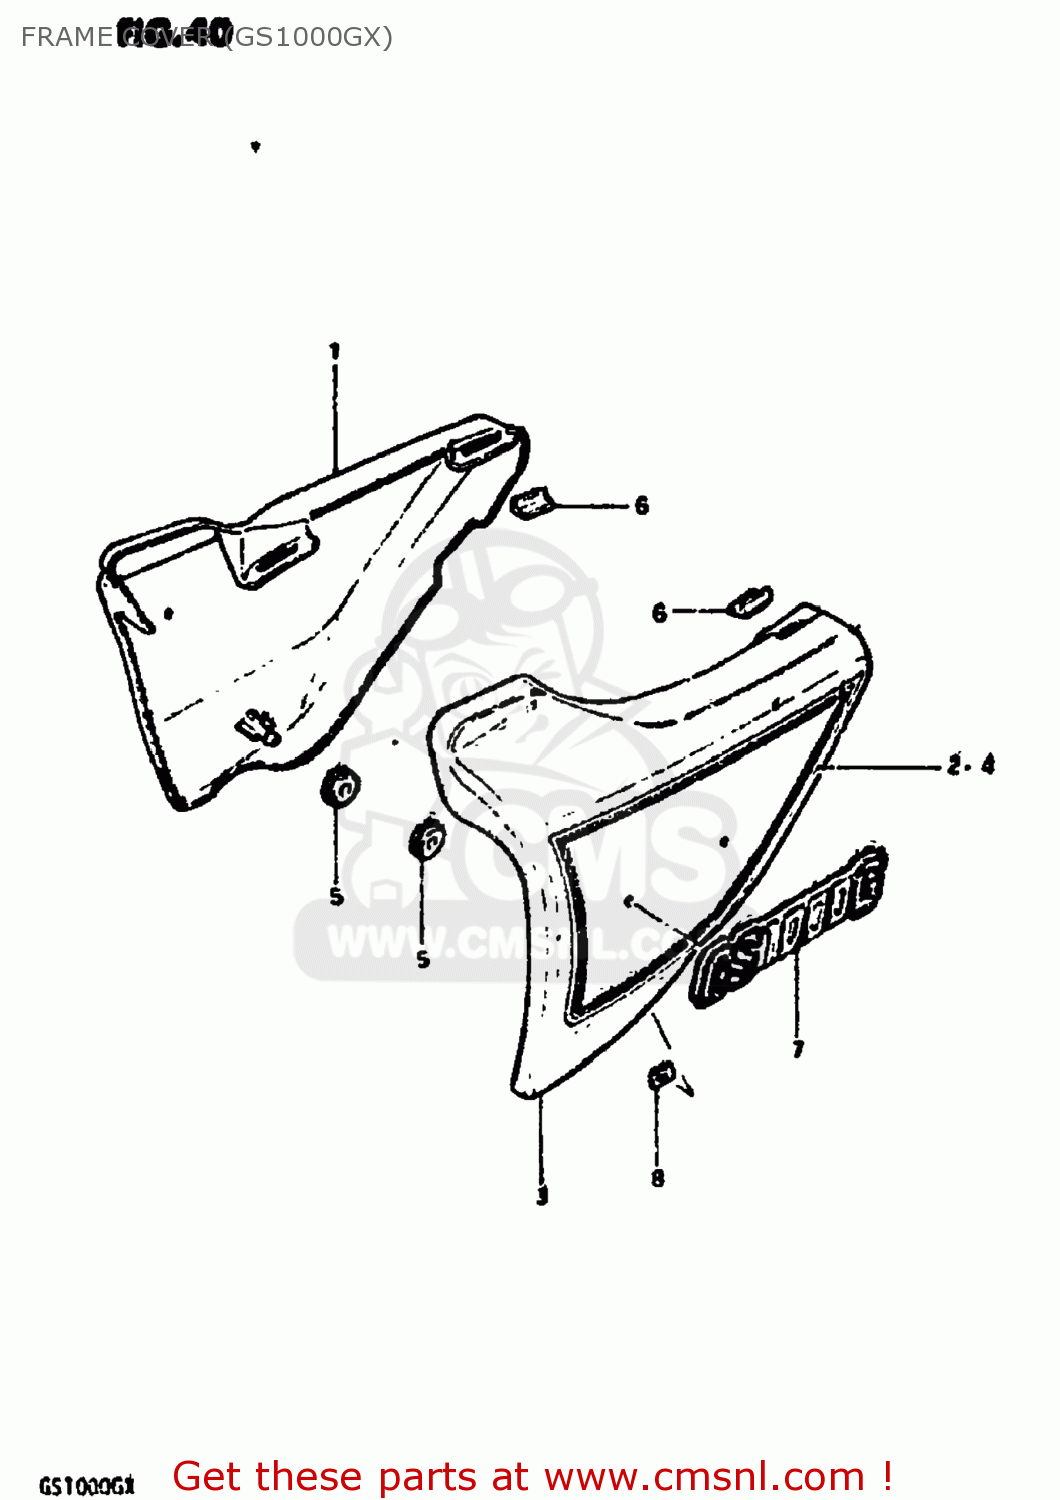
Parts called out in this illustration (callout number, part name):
1	COVER,FRAME,RIGHT
2	TAPE SET,FRAME COVER
3	COVER,FRAME,L
4	TAPE SET,FRAME COVER
5	CUSHION
6	CUSHION,FRAME COVER
7	EMBLEM,FRAME COVER
8	NUT
